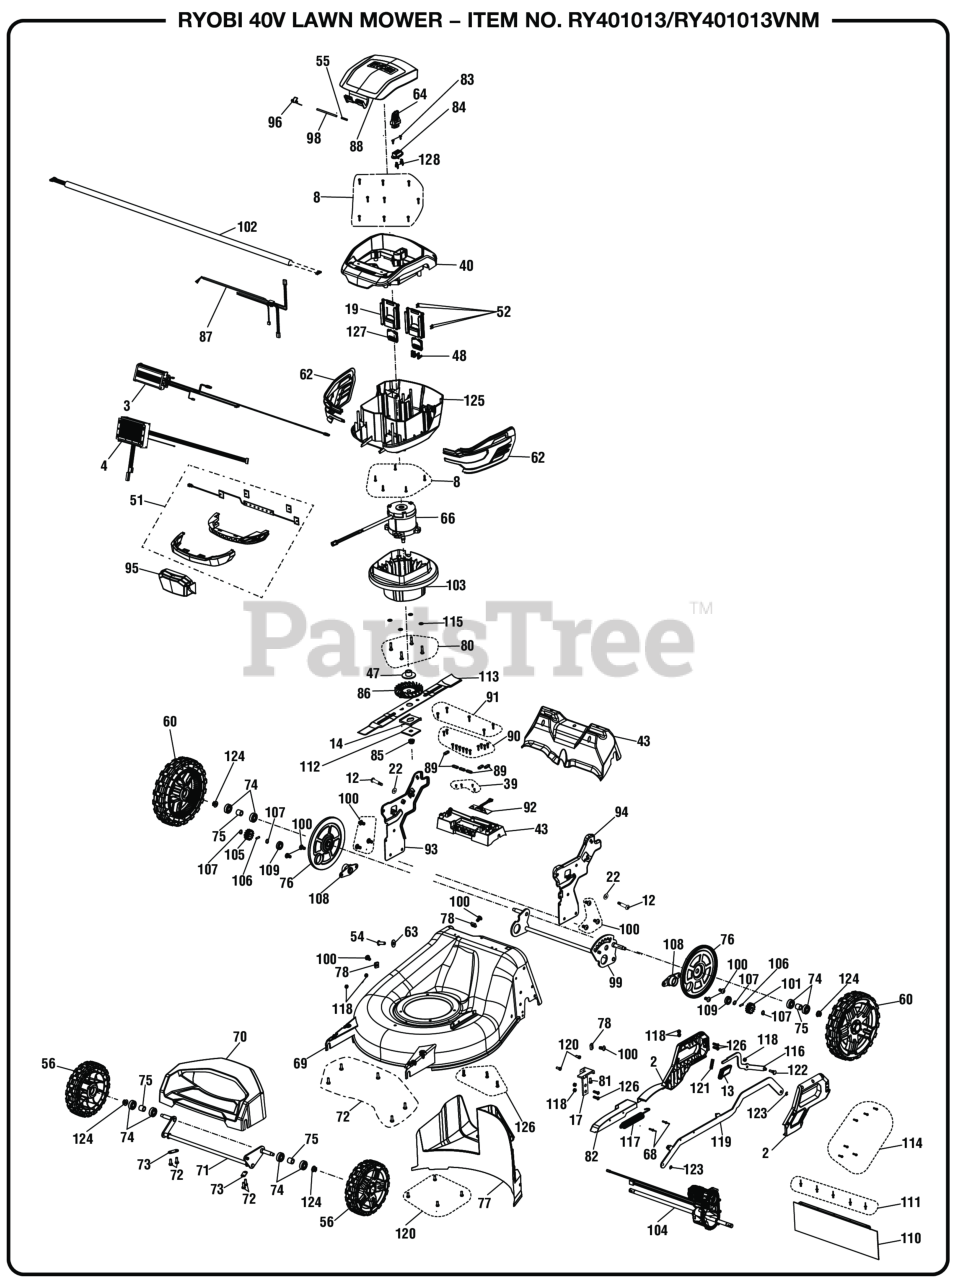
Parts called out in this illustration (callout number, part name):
2	Deck Height Adjustment Housing
3	Deck Height Adjustment Housing (Inc. Labels)
4	?Drive Motor Controller
8	Screw (M4 x 18 mm, T20 Torx Pan Hd.)
12	Screw (M8 x 33 mm, Hex Hd.)
13	Height Adjustment Trigger
17	Transmission Mount
22	Washer (ID8.5 x OD20.5 x 2 mm x 2t)
39	Screw (M3 x 8 mm, Pan Hd., Pan Hd)
40	Top Battery Housing Cover (Inc. Labels)
43	Bag Hanger
47	Motor Shaft Bushing
48	Common Foot Contact Plate
51	LED Circuit Board Assembly
52	Screw (M3 x 10 mm, T10 Torx Hd.)
55	Compression Spring
56	8 in. Wheel Assembly
60	10 in. Wheel Assembly
62	Battery Housing Vent Assembly
63	Washer (ID 4.3 x OD12 x 1.5t)
64	Key Assembly (Inc. Hangtag)
66	40V-DC Motor
69	21 in. Deck Assembly
70	Front Bumper Cover Assembly (Inc. Label)
71	Front Axle.
72	Screw (1/4-15 x 3/4 in., T30 Torx Pan Hd.)
73	Front Axle Mount
74	Ball Bearing (ID12 x OD32 x 10 mm)
75	Wheel Bushing
76	Wheel Cover
78	Square Nut (M8)
80	Bolt (M6 x 26 mm, Hex Hd.)
81	Screw w/Washer (M4 x 8 mm)
82	Spring Cover
83	Screw (M4.2 x 12 mm, T20 Torx Pan Hd.)
84	Key Holder
85	Blade Nut (M10 x 1.25, Hex Flange Hd.)
86	Motor Fan Blade Adapter
87	Inner Wire w/Terminal
88	Battery Cover Assembly
89	Wire Press Plate
90	Screw (M4 x 16 mm, T20 Torx Pan Hd.).
91	Screw w/Washer (M4 x 16 mm, T25 Torx Truss Hd.)
92	Signal Conversion Interface Board
93	Handle Bracket (Right)
94	Handle Bracket (Left)
95	Plug Cover Battery Housing (Front)
96	Battery Clear Cover Spring
99	Rear Axle w/Height Adjustment Plate
100	Screw (M8 x 16 mm, T40 Hex Hd.)
101	Drive Gear, Left
102	Main Wiring Harness
103	Motor Mount
104	Driven System Assembly
105	Drive Gear, Right
106	Drive Gear, Right
107	Retaining Ring
108	Drive Axle Bearing Sleeve
109	Ball Bearing (OD28.6 x ID12.7 x 8)
110	Rear Guard
111	STEEL RIVET DIA 3.9 X 8MM
112	Metal Blade Retainer
113	21 in. Blade
114	ST SCREW,STEEL CH M4.0X1.8 PH TORX
115	Washer (ID6.2 x OD15 x 0.08t)
116	Height Adjustment Hook
117	Extension Spring
118	Lock Nut (M6 x 6 mm)
119	Height Adjustment Linkage
120	Screw (M6 x 14 mm, Hex Soc. Hd.)
121	Height Adjustment Trigger Spring
122	Clutch Shoulder Bolt (M6 x 22.5 mm, Hex Hd.)
123	E-Ring (ID 6 mm)
124	Lock Nut (3/8-16, Flange)
125	Battery Housing (Bottom)
126	Screw (M6 x 20 mm, T27 Torx Button Hd.)
127	Common Foot Cover
128	Female Terminal
